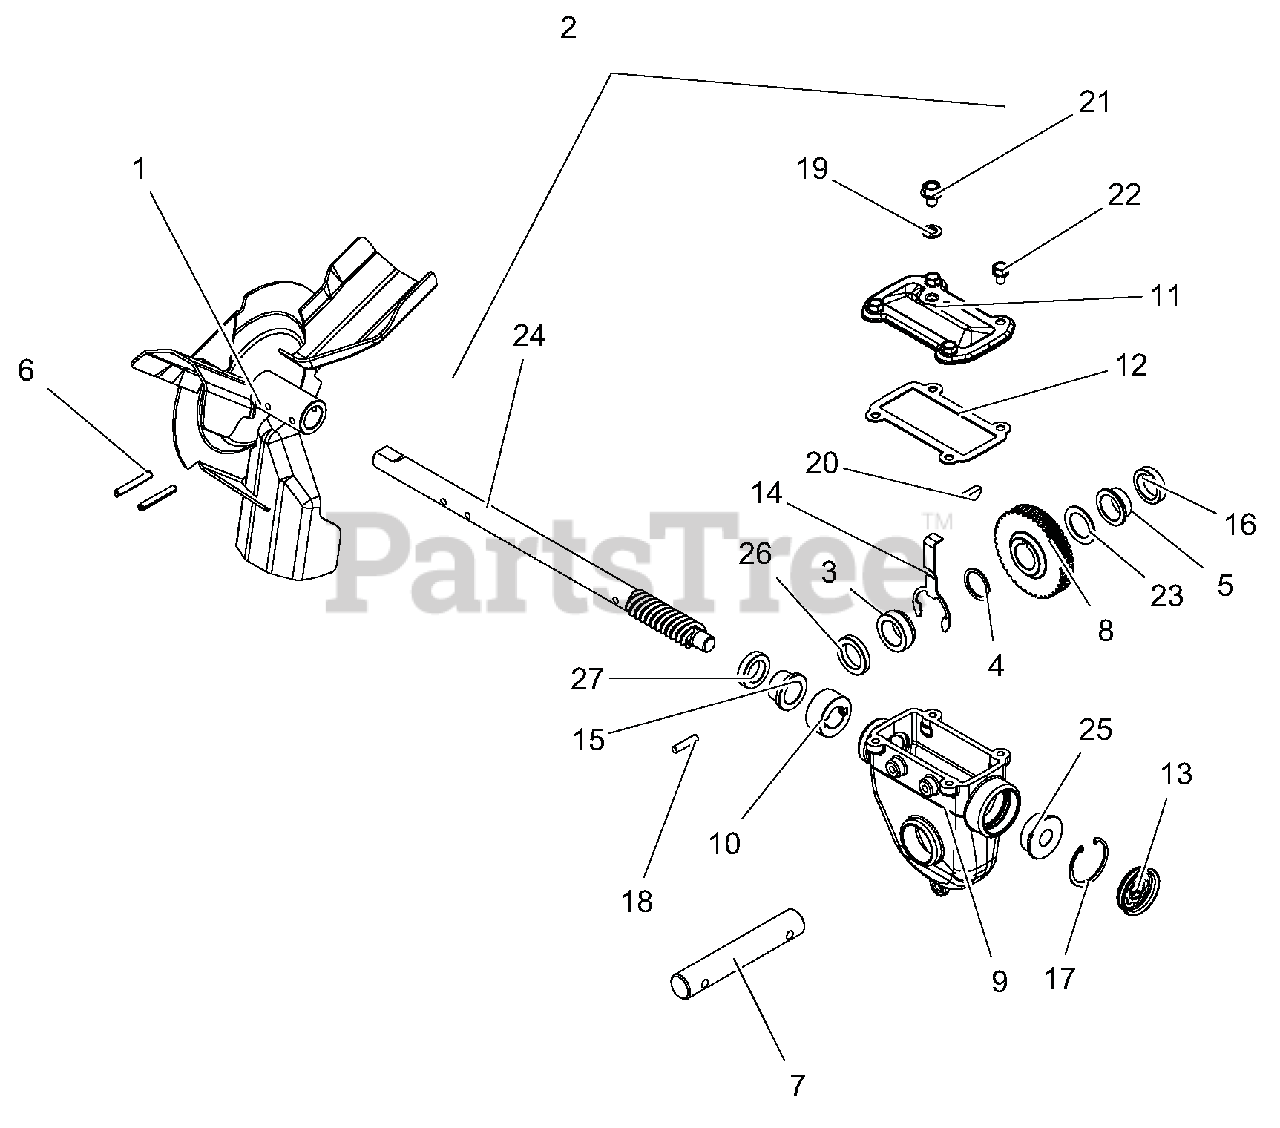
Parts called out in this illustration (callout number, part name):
1	IMPELLER, 3 BLADE-14"
2	GEAR CASE ASSY - DLX IRON
3	BSHG-FLG LARGE, RIGHT
4	WSHR-FL-STL 1.010X1.250X.068YZ
5	BSHG-FLG 1.006X1.128X.555X1.45
6	PIN-ROLL .250X1.75
7	RAKE SHAFT, SHORT-COMMON
8	WORM SHAFT & GEAR
9	GEARCASE, LARGE MACHINED
10	THRUST COLLAR, .875"ID SLIPFIT
11	COVER, TOP - LARGE IRON
12	GASKET, TOP - LARGE GEARCASE
13	COVER, GEAR CASE 1.75"
14	BUSHING RETAINER, LARGE
15	BSHG-FLG .879X1.128X.75X1.45
16	SEAL-OIL .999X1.375X.312 TBC29
17	RG-RTNG-INT 1.750X.062
18	PIN-STR .250X1.12 6150
19	WSHR-BND-SEAL .38X.75X.11 GALV
20	KEY-WDRF .25X.875 HRD #A
21	@SCR-ROLOK .38-16X.50 HWH YWZC
22	BOLT, SEMS .31-18X.50 GR5 YWZC
23	WSHR-FL-STL 1.010X1.505X.062YZ
24	WORM SHAFT & GEAR
25	BSHG-FLG .628X1.503X.58X1.725
26	SEAL-OIL .999X1.500X.250 TBC29
27	SEAL-OIL .873X1.375X.312 TBC29
